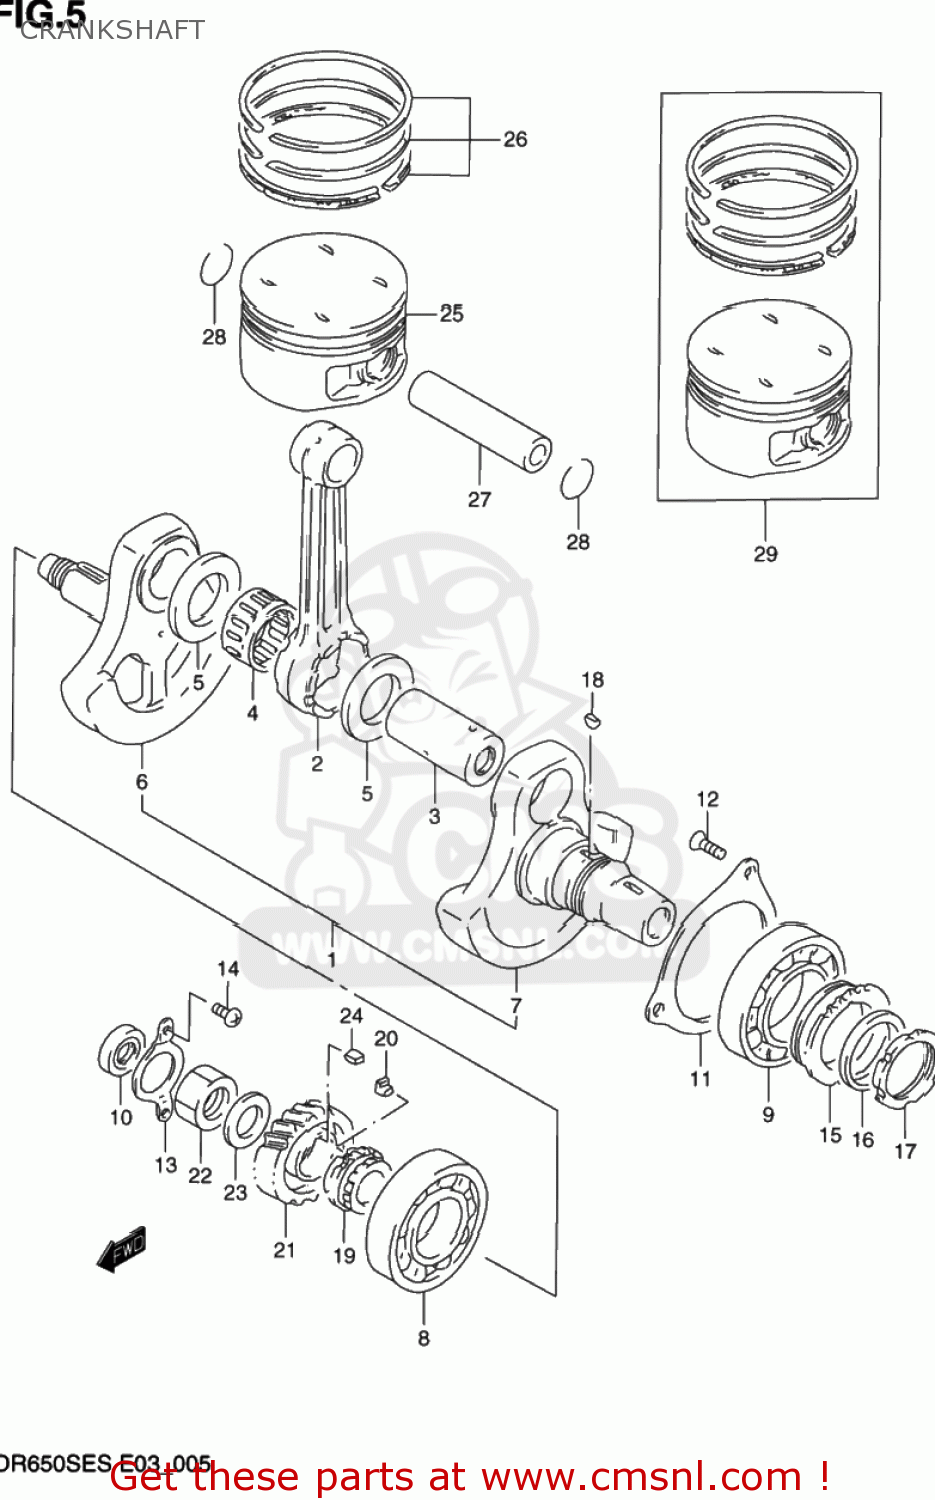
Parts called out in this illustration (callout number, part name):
1	CRANKSHAFT ASSY
2	ROD,CONNECTING
3	PIN,CRANK
4	BEARING
5	WASHER(35X55X1)
6	CRANKSHAFT,R
7	CRANKSHAFT,L
8	BEARING(35X80X21)
9	BEARING
10	SEAL,OIL(16X30X6)
11	RETAINER,CRANKSHAFT BEARING,L
12	SCREW
13	RETAINER,CRANKSHAFT BEARING,R
14	SCREW
15	SPROCKET,BALANCER DRIVE
16	WASHER
17	NUT,BAL DRIVE SPRKT
18	KEY
19	SPROCKET,CAM CHAIN DRIVE
20	KEY,SPROCKET
21	GEAR,PRIMARY DRIVE
22	NUT (20MM)
23	WASHER
24	KEY
25	PISTON
26	RING SET,PISTON
27	PIN,PISTON
28	CIRCLIP
29	PISTON SET (OS:0.5)
